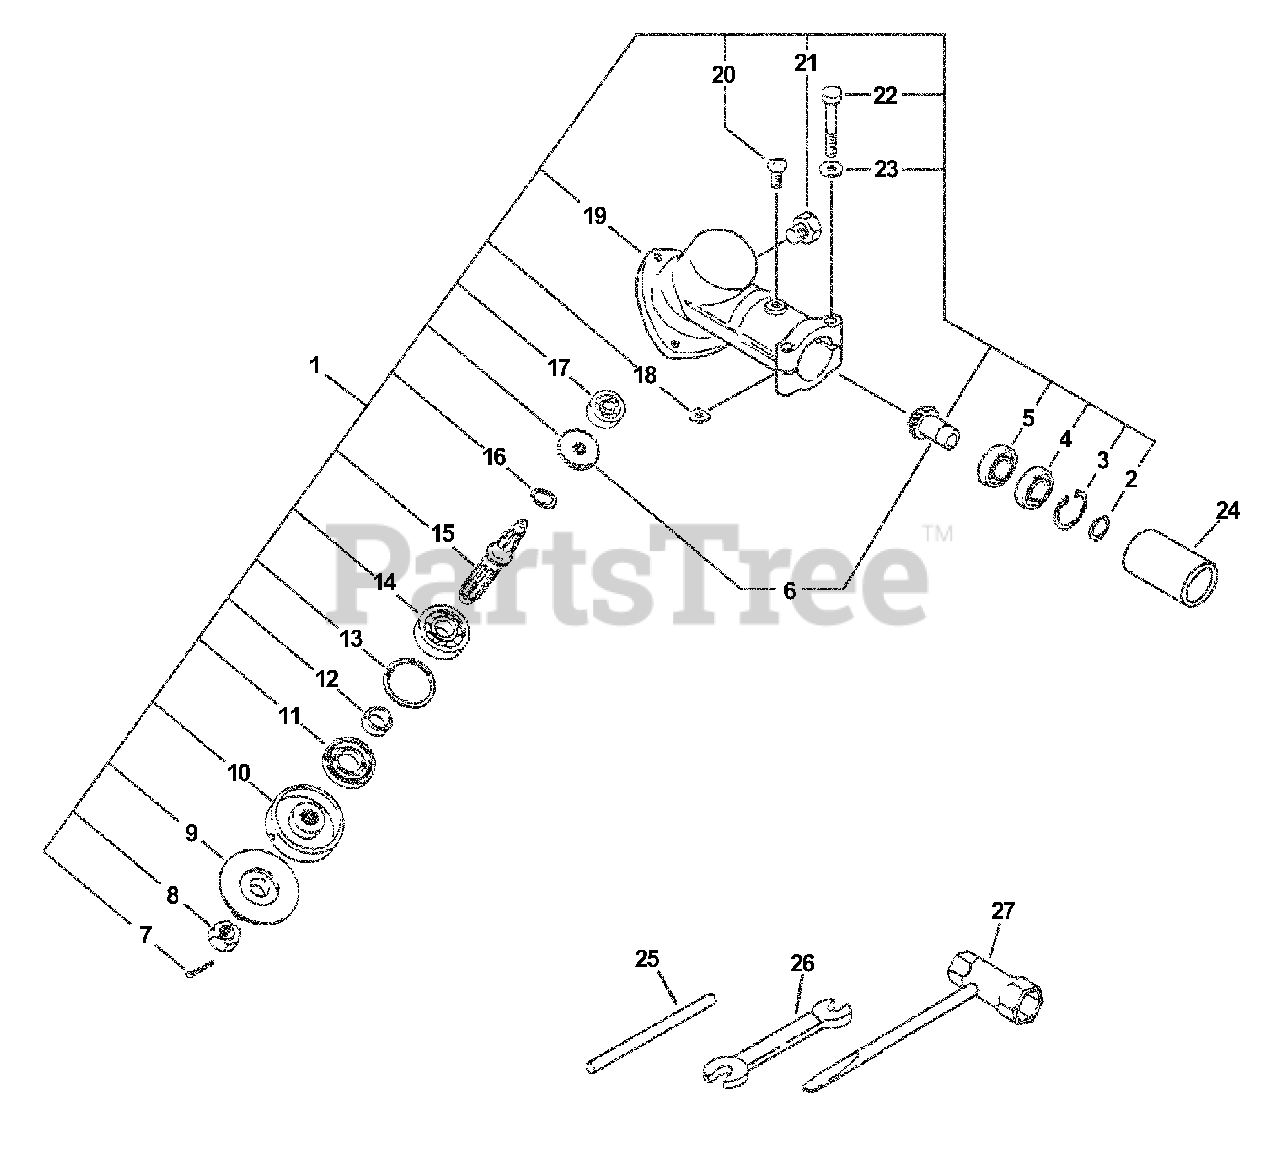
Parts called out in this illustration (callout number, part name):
1	GEAR CASE ASSY
2	RING, SNAP Ø10
3	RING, SNAP Ø22
4	BEARING, BALL 6900Z
5	BEARING, BALL 6900
6	GEAR SET
7	PIN, COTTER 2×22
8	NUT 10×1.25 LH
9	PLATE, ADAPTOR - LOWER
10	PLATE, ADAPTOR - UPPER
11	SEAL, OIL 22
12	SPACER 11.8×15×9
13	RING, SNAP Ø32
14	BEARING, BALL - 6201 C3
15	SHAFT, GEAR
16	RING, SNAP Ø12
17	BEARING, BALL 609
19	HOUSING, GEAR CASE
20	SCREW 5×14
21	BOLT M8×8
22	BOLT 5×30
23	WASHER, FLAT 5.5×10×0.8
25	TOOL, LOCKING 5×120 MM
26	SPANNER 8×10
27	T-WRENCH 17x-19 L200
